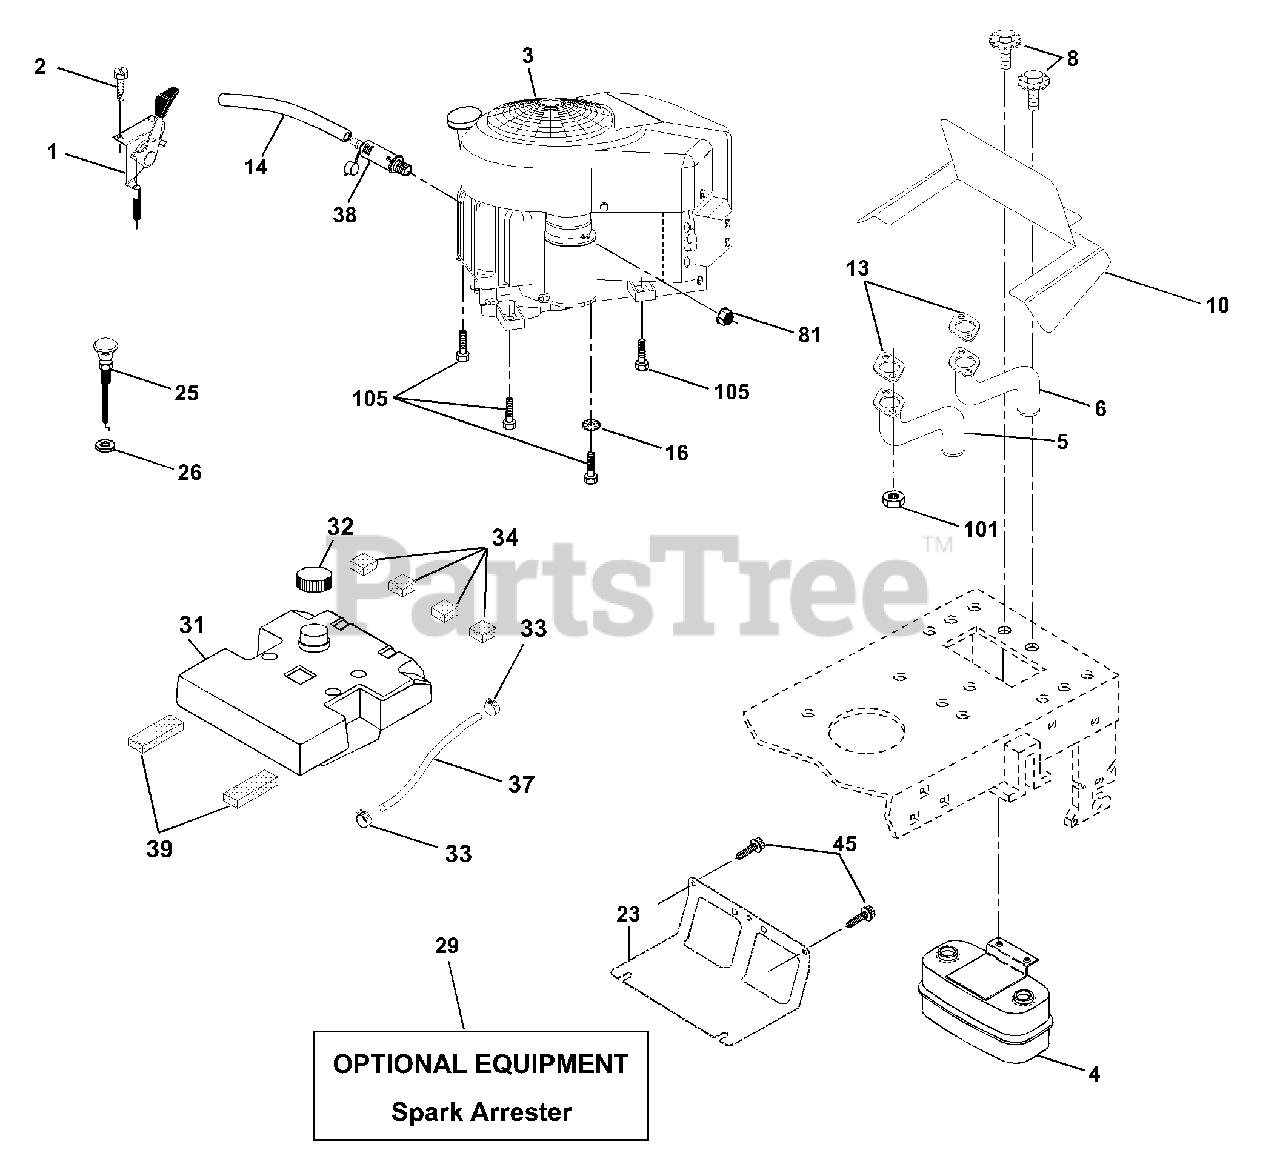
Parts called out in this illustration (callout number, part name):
1	Control Throt Flg
2	Screw Hex Thd Cut 1/4-20x5/8 T
4	Muffler Asm Twin Lo-Tone
5	Exhaust Tube Lh
6	Exhaust Tube Rh
8	Bolt 5/16-18unc x 3/4 W/Sems
10	Shield Browning
13	Gasket Muffler
14	Tube Drain Oil Easy
16	Washer Lock Ext Tooth 3/8
23	Shield Browning
25	Choke Control
26	Nut, Keps 3/8-24 Unf
29	Kit Spark Arrestor (Flat Scrn)
31	Tank Fuel 3 50 Rear
32	Cap Asm Fuel Gauge
33	Clamp Hose Blk
34	Pad, Spacer
37	Line Fuel
38	Plug Drain Oil
39	Pad, Idler
45	Screw Hexwsh Thdr 3/8-16 x 3/4
81	Nut Keps Hex 1/4-20
101	Nut Flange M8-1.25
105	Screw 3/8-16 x 1
